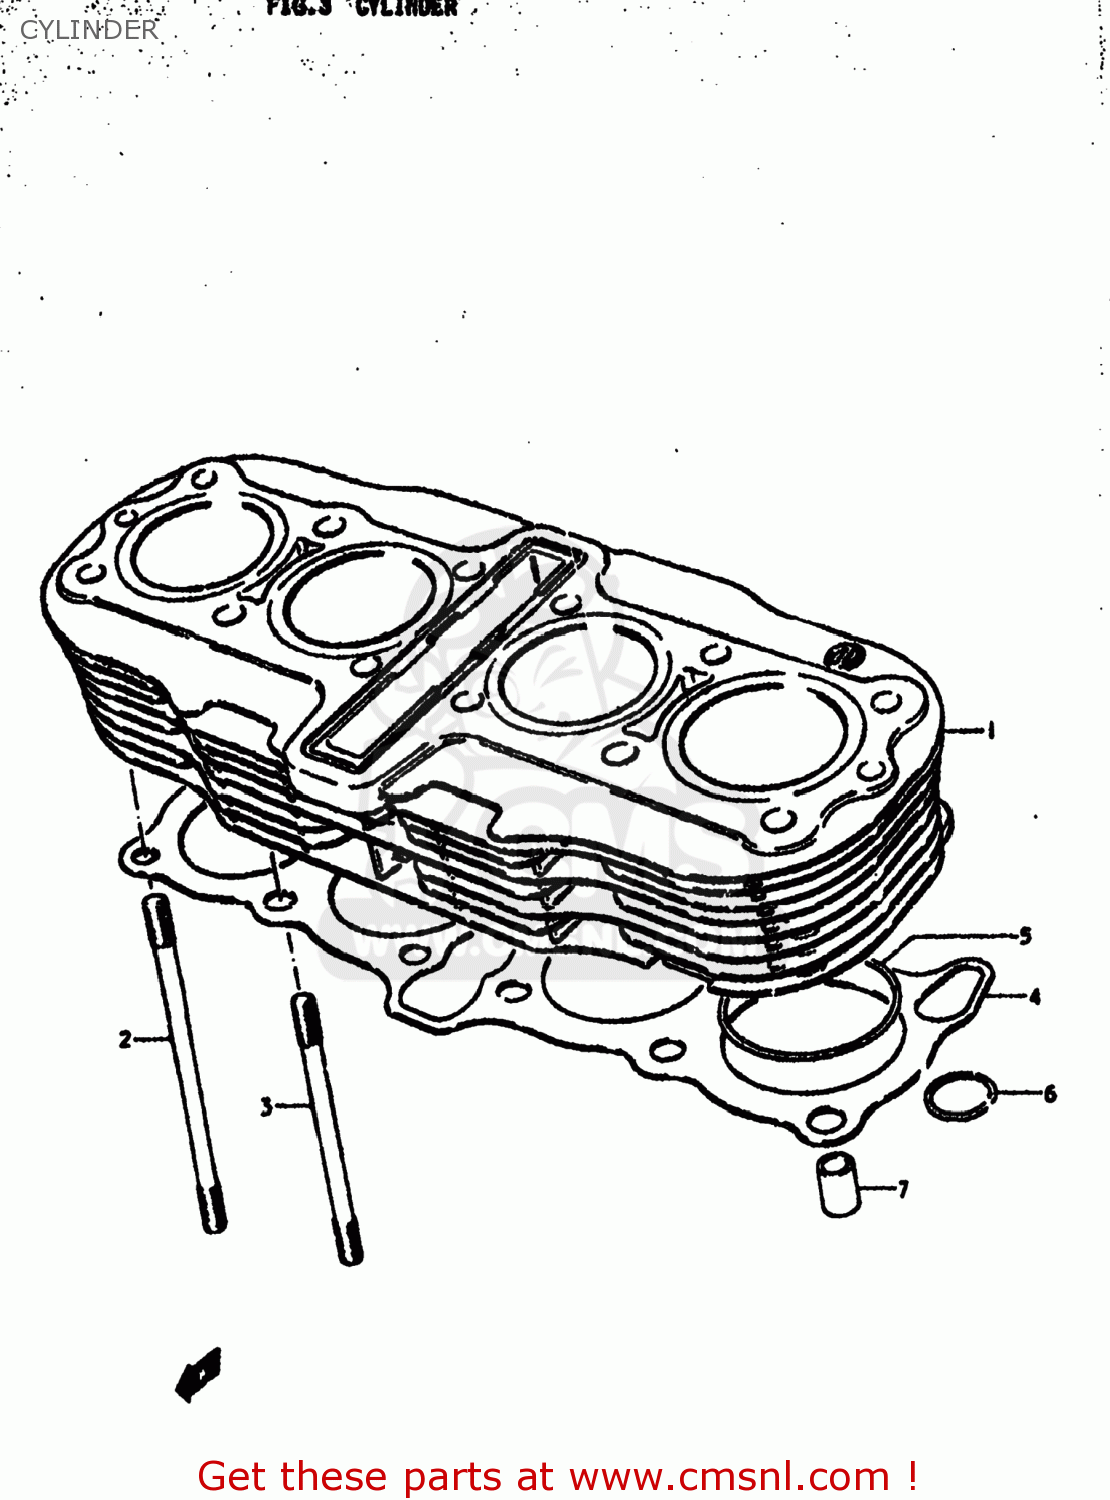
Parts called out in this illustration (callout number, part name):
1	CYLINDER
2	STUD
3	STUD
4	GASKET,CYLINDER (MCA)
5	O RING(D:2,ID:61)
6	O RING(D:2.4)
7	PIN
